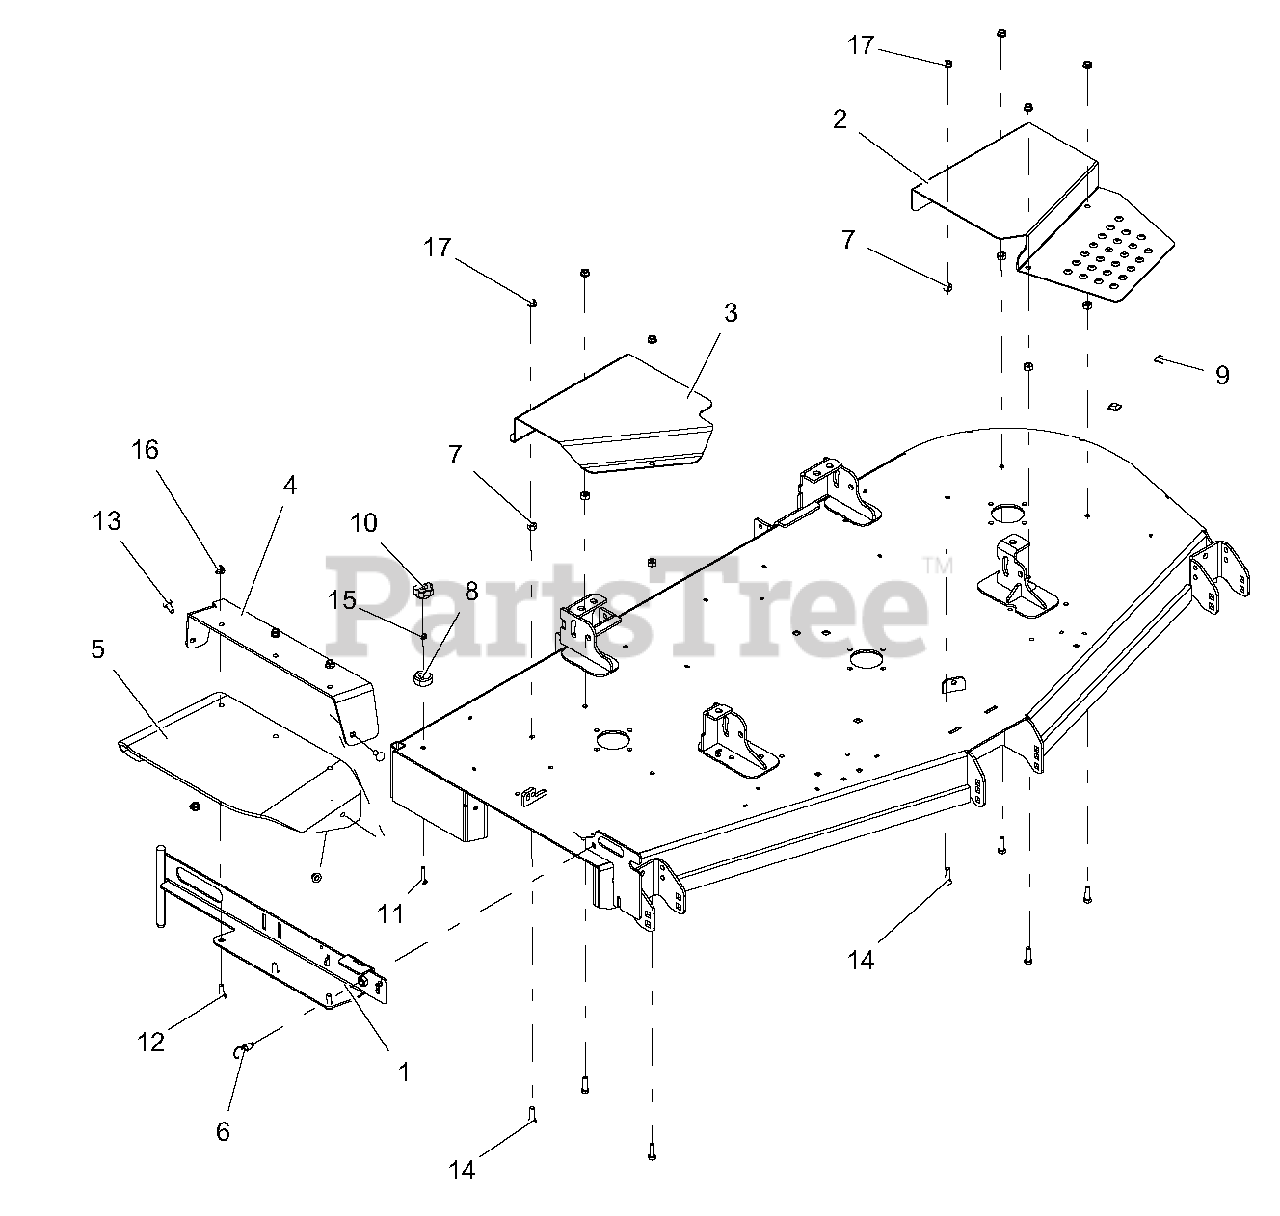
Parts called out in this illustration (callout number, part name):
1	WLDMT, 66"-72" DISCH CHUTE MTG-RED
2	GUARD, 72" LH DECK BELT-RED
3	GUARD, 72" RH DECK BELT-RED
4	SUPPORT, CHUTE MOUNTING BRACKET-RED
5	CHUTE, RUBBER DISCHARGE
6	PULL PIN,.50-13THDX.310 PLNGR
7	NUT-HEAVY HEX .38-16 YWZC
8	BUMPER, RECESSED 1.50 X .63 W/.31 HOLE
10	KNOB, CLAMPING
11	@BLT-RDHDSQNK .31-18X1.50 G5 YWZC
12	@BLT-RDHDSQNK .38-16X1.25 G5 YWZC
13	@BLT-RDHDSQNK .38-16X1.00 G5 YWZC
14	BLT-HEX .38-16X1.25 GR5 YWZC
15	@NUT-LK-CTR .31-18 YWZC
16	NUT-LK-NYL-FLG .38-16 YWZC
17	@NUT-SPNLK-FLG .375-16 YWZC
